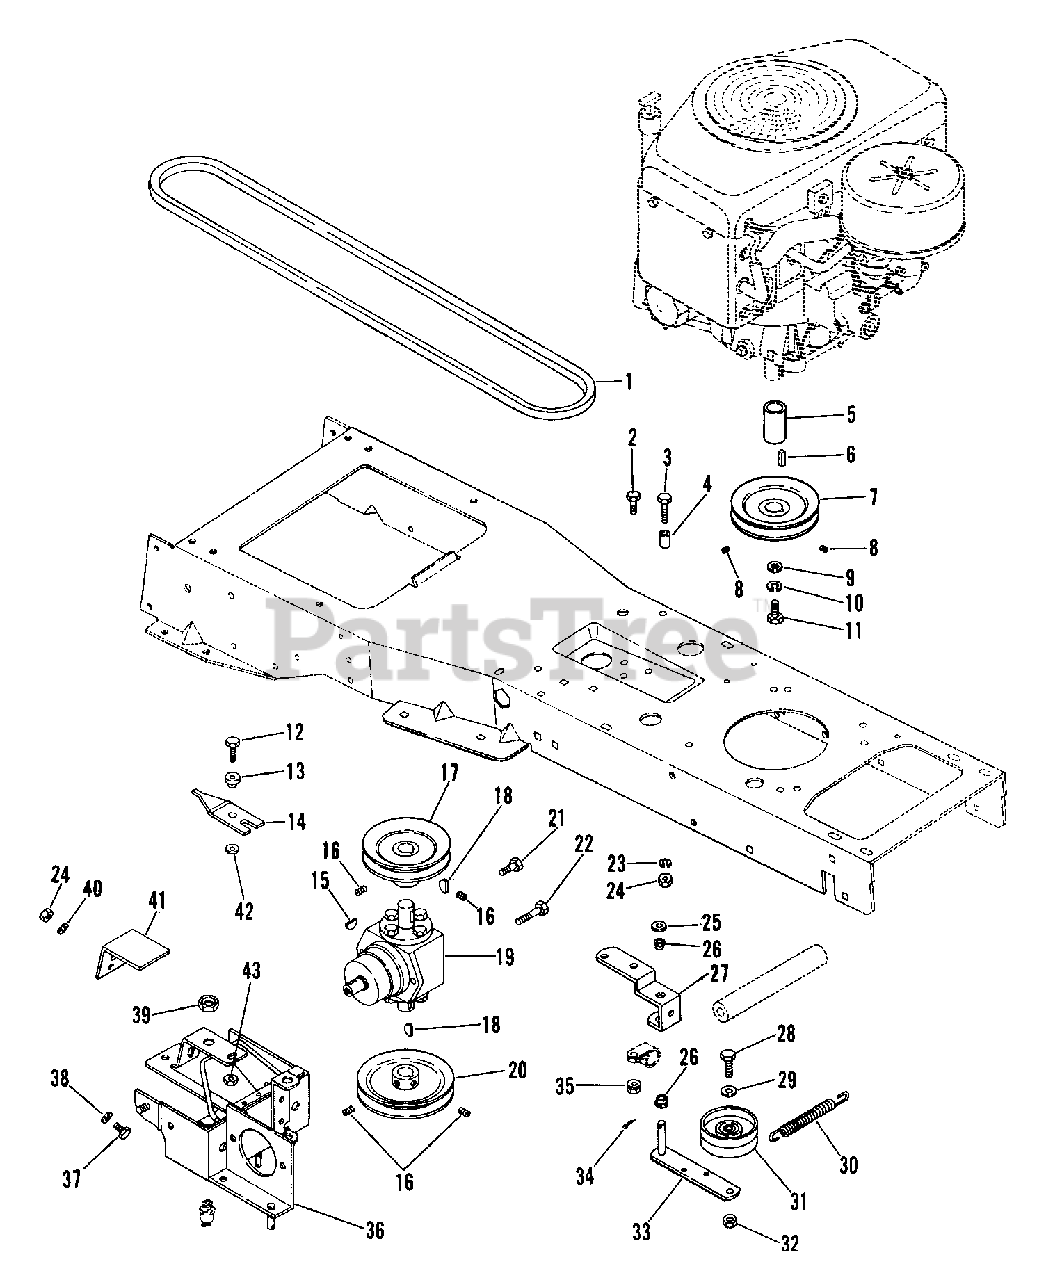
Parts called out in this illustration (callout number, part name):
1	V-BELT, 5L-RAW EDGE
2	BLT-RDHDSQNK .31-18X.75 SHT PL
3	BLT-HEX .31-18X1.50 PL GR2
4	SPACER .344X.500X.875
6	KEY-STR .25X.875X.25
7	PLY-? 5.0X1.0
8	SCR-SET .32-18X.25 SKHCUP OH
9	WSHR-FL-STL .469X1.380X.125
10	WSHR-LK .438X.133 HVY
11	BLT-HEX .44-20X1.00 GR5
12	BLT-HEX .31-18X1.00 PL GR5
13	SHOULDER SPACER
14	SWITCH ACTUATOR LEVER
15	KEY-WDRF .188X.625X.25 SAE 61
16	SCR-SET .32-18X.38 SKHCUPNL OH
17	PLY-V 5.00 X .87 W/KEY CLARK
18	KEY-WDRF .188X.75X.313 SAE 9
19	T DRIVE HEAD ASSEMBLY
20	PLY-V 5.50 X .88 W/KEY CLARK
21	BLT-HEX .38-16X1.25 PL GR5
22	BLT-HEX .38-16X1.75 PL GR5
23	WSHR-LK .312X.097 PL HVY
24	NUT-HEX .312-18
25	WSHR-FL-STL.406X.812X.065PL
26	BSHG-FLG .372X.500X.312X.625NY
27	IDLER PIVOT
28	BLT-HEX .38-16X1.75 PL GR2
29	WSHR-FL-STL .382X.812X.062
30	SG-TENS .087X.55X6.13 WLD 10
31	IDLER-FLAT 3.25 X .38 NWHAMSHR
32	NUT-LK-CTR .375-16 GR A PL
33	IDLER ARM
34	PIN-COTR .12X.75 PL
35	NUT-FLG. .312-18 PL
36	TRANSAXLE SUPPORT
37	BLT-HEX .31-18X.75 PL GR2
38	WSHR-FL-STL.344X.688X.065PL
39	NUT- .562-18
40	WSHR-LK .313X.078 PL MED
41	RETAINER-SWITCH LEVER
42	WSHR-FL-STL.344X.688X.065PL
43	NUT-LK .312-18 GR A PL
